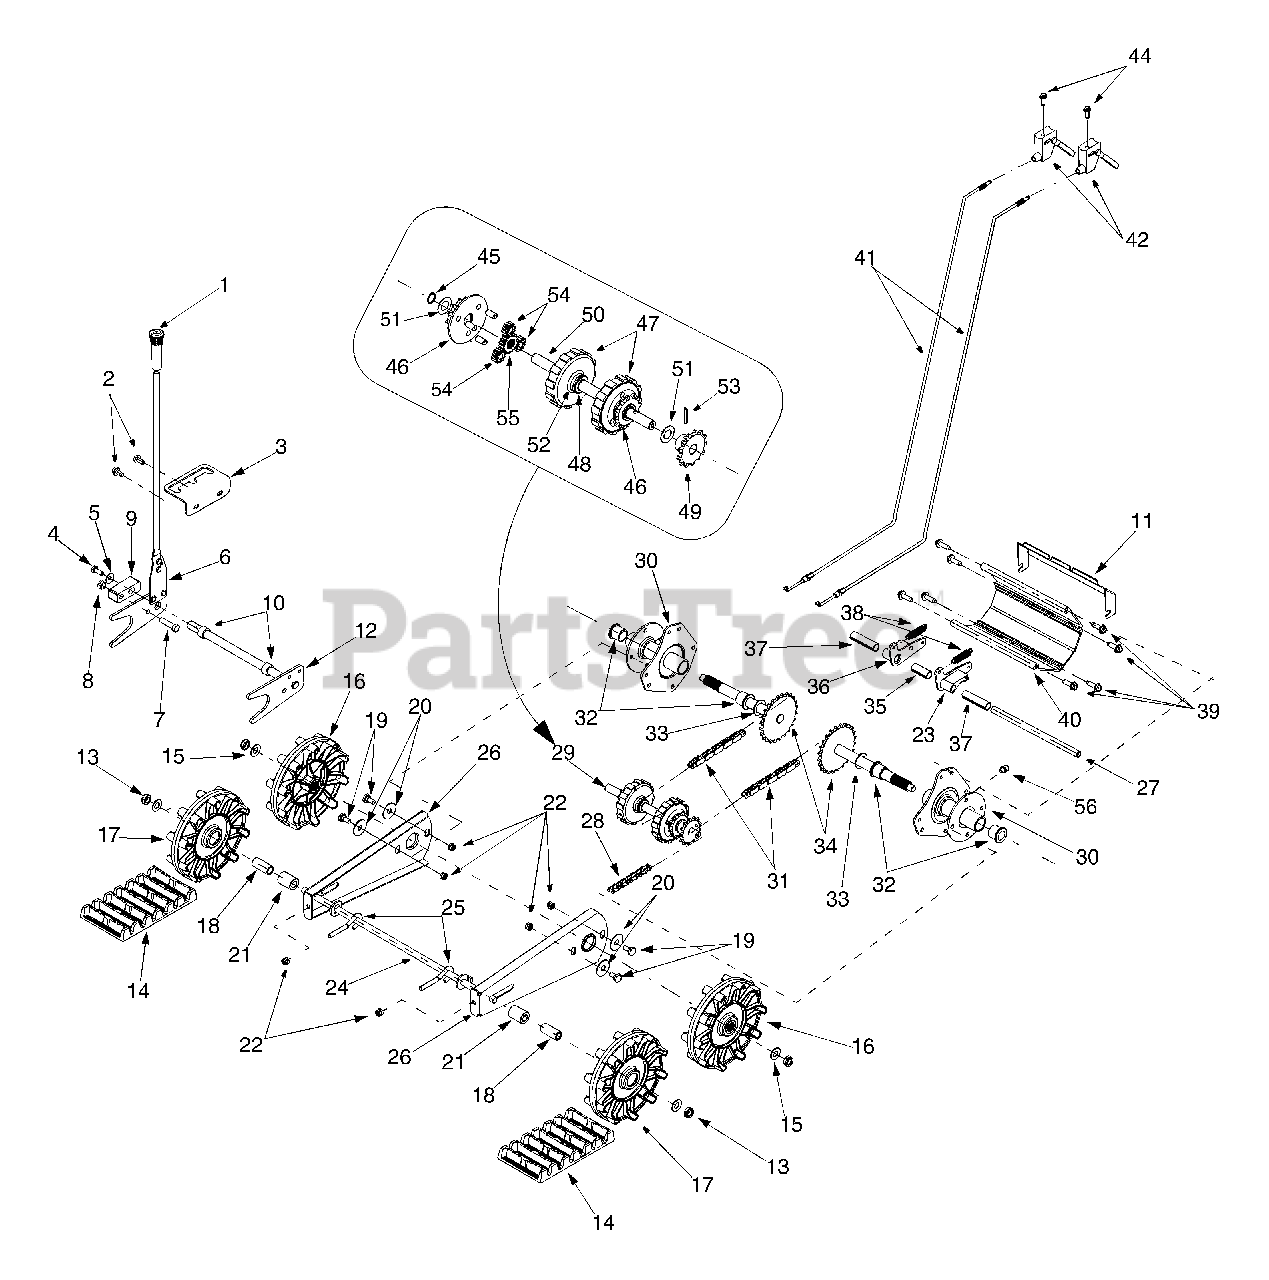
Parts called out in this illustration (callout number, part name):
2	Tap Screw, 5/16-18 x.625
4	Hex Cap Screw, 5/16-24 x.75
5	Bell Washer
7	Hex Cap Screw, 3/8-24 x 1.5
8	Hex Nut, 3/8-24
9	Lift Shaft Drive
10	Spacer
13	Jam Nut, 1/2-20
14	Snow Track
15	Flat Washer
16	Track Drive Wheel
17	Track Idler Wheel
18	Spacer
19	Screw,.435 x.178-5/16 x.56
20	Flat Washer
21	Spacer
22	Flange Lock Nut, 5/16-18
23	LH Dogg Assembly
25	Eye Bolt
27	Actuator Shaft
28	Chain
29	Track/Steering Shaft Assembly
31	Chain
32	Flange Bearing
33	Flat Washer
34	Axle Assembly
35	Spacer
36	RH Dogg Assembly
37	Spacer
38	Extension Spring
39	Tap Screw, 5/16-18 x 1
40	Track Housing
41	Steering Cable
42	Steering Trigger
44	Screw, #10-24 x 1.375
45	Retaining Ring
46	Carrier Assembly
47	Ring Gear
48	Retaining Ring
49	13-Tooth Sprocket
50	Track Steering Drive Shaft
51	Flat Washer
52	Flat Washer
53	Spiral Pin
54	12-Tooth Gear
55	18-Tooth Gear
